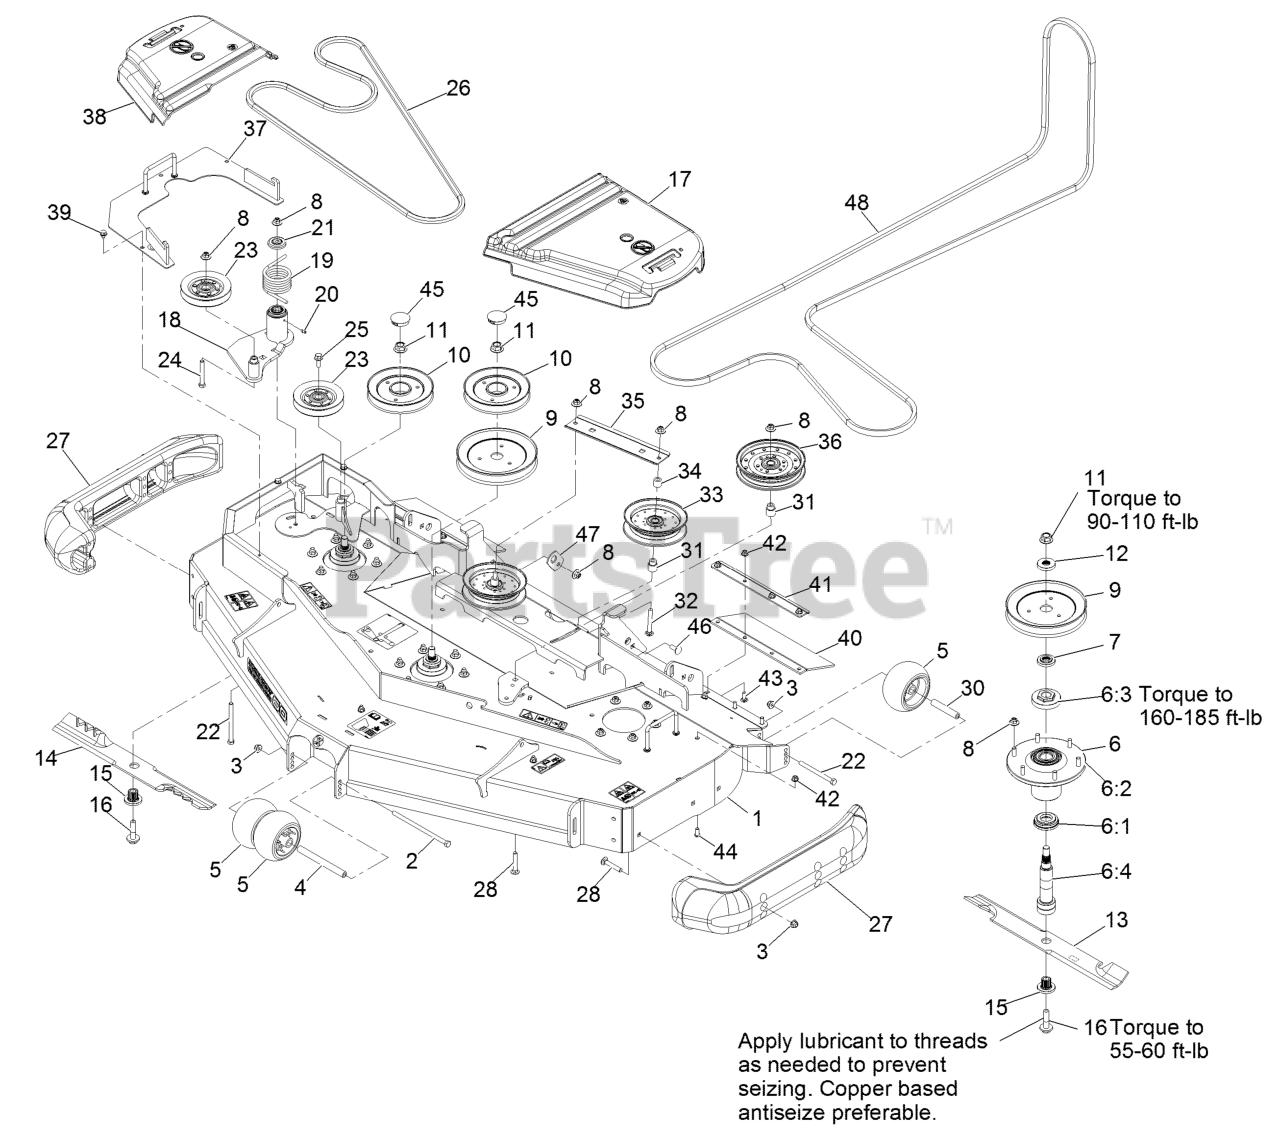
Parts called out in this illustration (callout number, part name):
1	DECK-RD60, W/DECALS
2	SCREW-HH
3	NUT-HF, NI
4	SPACER-WHEEL
5	ROLLER-SCALP, ANTI
6	ASM,SPINDLE HOUSING
6:1	GUARD,BOTTOM
6:2	ASM,CUTTER HOUSING
6:3	NUT, SPINDLE 7/8-14
6:4	SPINDLE,DOUBLE SPLINE
7	SPACER,SPLINED STEPPED
8	Nut-Nyloc 3/8-16 Flg
9	SHEAVE,BLADE DRIVE 7.25
10	SHEAVE-RD, REVERSE DRIVE
11	NUT-FLANGE, CENTERLOCK
12	SPACER,SPLINED
13	Blade-Extreme 2, 20.50"
14	Blade-Extreme 2-20.50, Rd60
14	Blade-Low Lift 20.5, Rd60
15	BUSHING,SPLINED
16	SCREW,SEMS 1/2-20 X 2.19
17	COVER-BELT, LH
18	IDLER ASM
19	SPRING-TORSION
20	FITTING-GREASE
21	GUARD-TOP
22	SCREW-HH
24	SCREW-HH
25	SCREW-HHF
26	BELT
27	SKID-BUMPER, DECK
28	Bolt-Carriage 3/8-16 X 2 1/4
30	TUBE-SPANNER
31	BUSHING-IDLER
32	SCREW-CARR
35	GUIDE-RD BELT
37	COVER-DRIVE REVERSE
38	COVER-BELT, RH
40	GUARD-TIRE
41	SUPPORT-OUTER FLAP
42	NUT-HF, NI
43	SCREW-CARR
44	SCREW-HSBH
45	PLUG,BLACK NYLON 1.75
46	BOLT-CARR
47	PLATE,DECK STRUT
48	BELT-V
